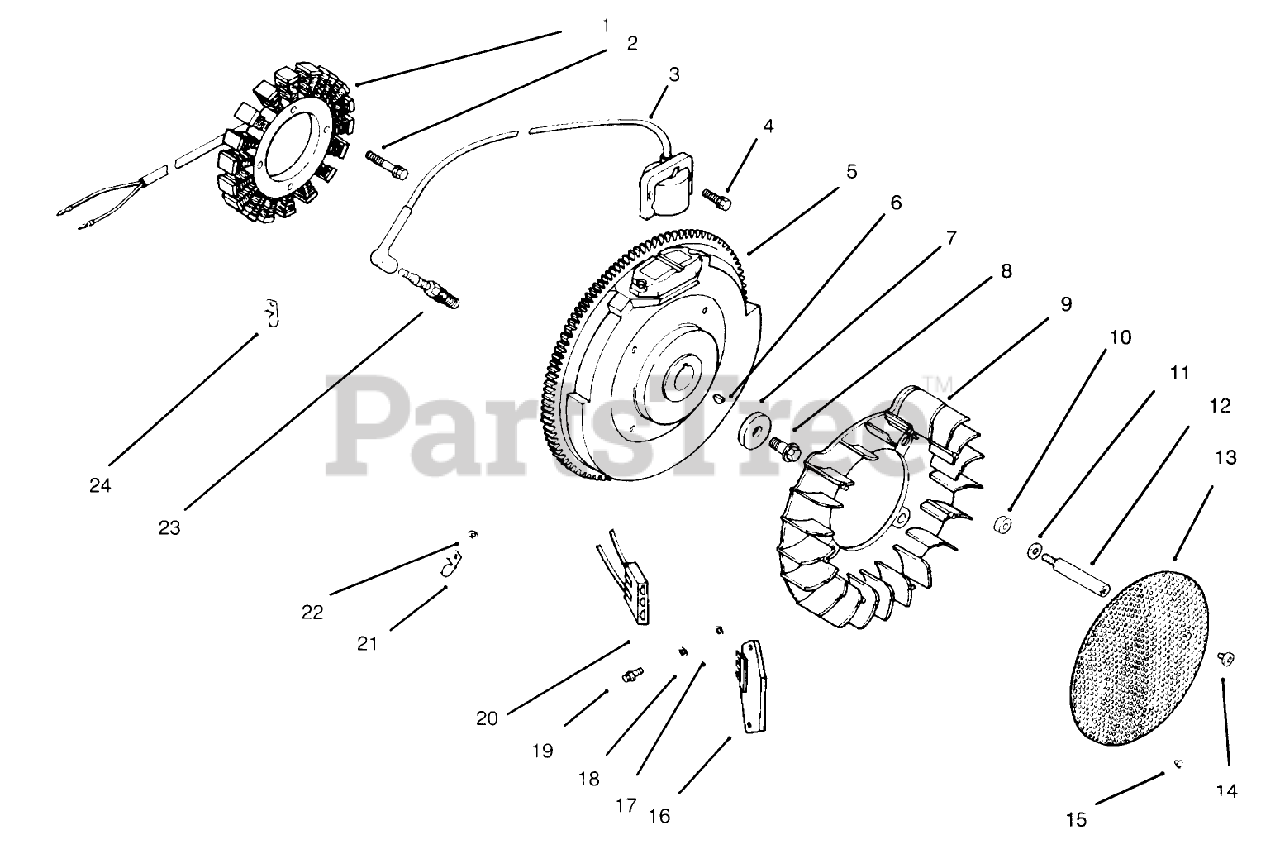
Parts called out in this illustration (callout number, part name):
1	Stator-15 Amp
2	Screw
3	Module-Ignition
4	Screw
5	Flywheel
6	Key
7	Washer
8	Screw
9	Fan
10	Spacer
11	Washer
12	Stud
13	Screen-Grass
14	Screw
15	Screw-Set
16	Rectifier-Regulator
17	Washer
18	Washer
19	Screw
20	Connector
21	Clip
22	Washer
23	Plug-Spark
24	Clip
